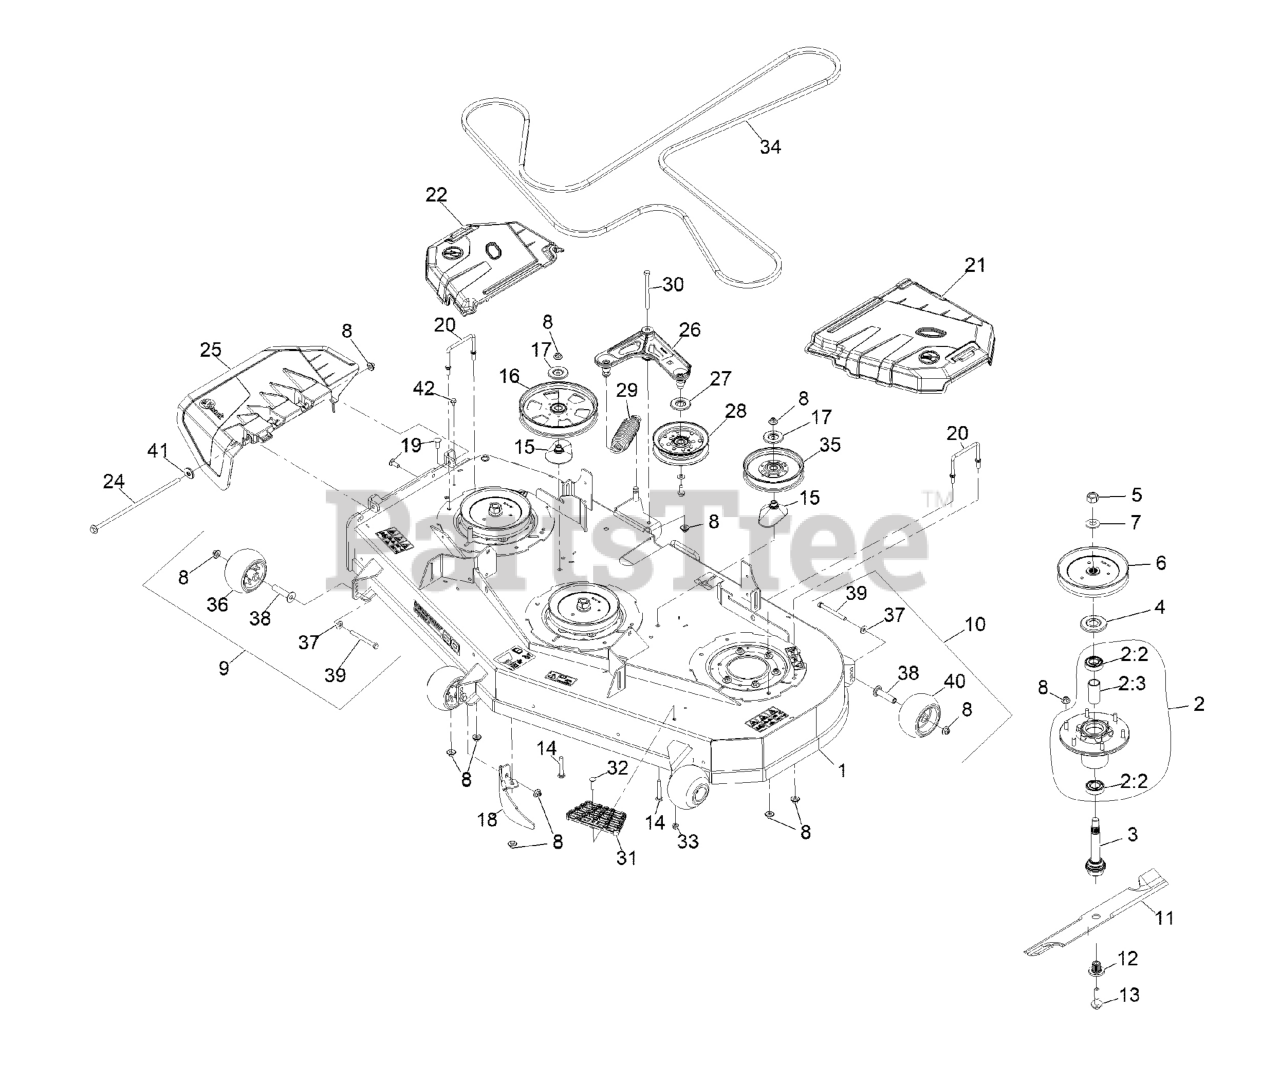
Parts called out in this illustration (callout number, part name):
1	ASM-Deck W/Decals 604
2	ASM-CUTTER HSG WITH BEARINGS
2:2	BEARING-BALL
2:3	SPACER-BEARING
3	ASM-SPINDLE AND SEAL
4	GUARD-BEARING, TOP
5	NUT-HEX
6	SHEAVE,BLADE DRIVE 7.25
8	Nut-Nyloc 3/8-16 Flg
9	KIT, ANTI-SCALP ROLLER
10	KIT-ANTISCALP ROLLER
11	Blade-Extreme 2, 20.50"
12	BUSHING,SPLINED
13	SCREW,SEMS 1/2-20 X 2.19
14	SCREW-CARR
15	SPACER-PULLEY
16	PULLEY-IDLER, FLAT
17	SHIELD-DUST
18	DOGLEG - LZ60
19	SCREW-CARR
20	WIREFORM-COVER
21	SHIELD, LT
22	SHIELD, RT
24	Pin, Chute
25	Chute-Deck Discharge
26	ASM-IDLER ARM W/BEARINGS
27	SHIELD-GUARD, DUST
28	IDLER-PULLEY, FLAT
29	SPRING-EXTENSION
30	SCREW-HH
31	STEP-DECK
32	Bolt-Carriage 5/16-18 X 1 1/4
33	NUT-HF, NI
34	BELT-V
35	IDLER-PULLEY, FLAT 6.00X1.00
36	ROLLER-SCALP, ANTI
37	WASHER-BELLEVILLE
38	AXLE, ROLLER
39	SCREW-HH 3/8-16 X 3 3/4 GR 8
40	ROLLER-SCALP, ANTI
41	Retainer, Chute
42	SCREW-HHF
